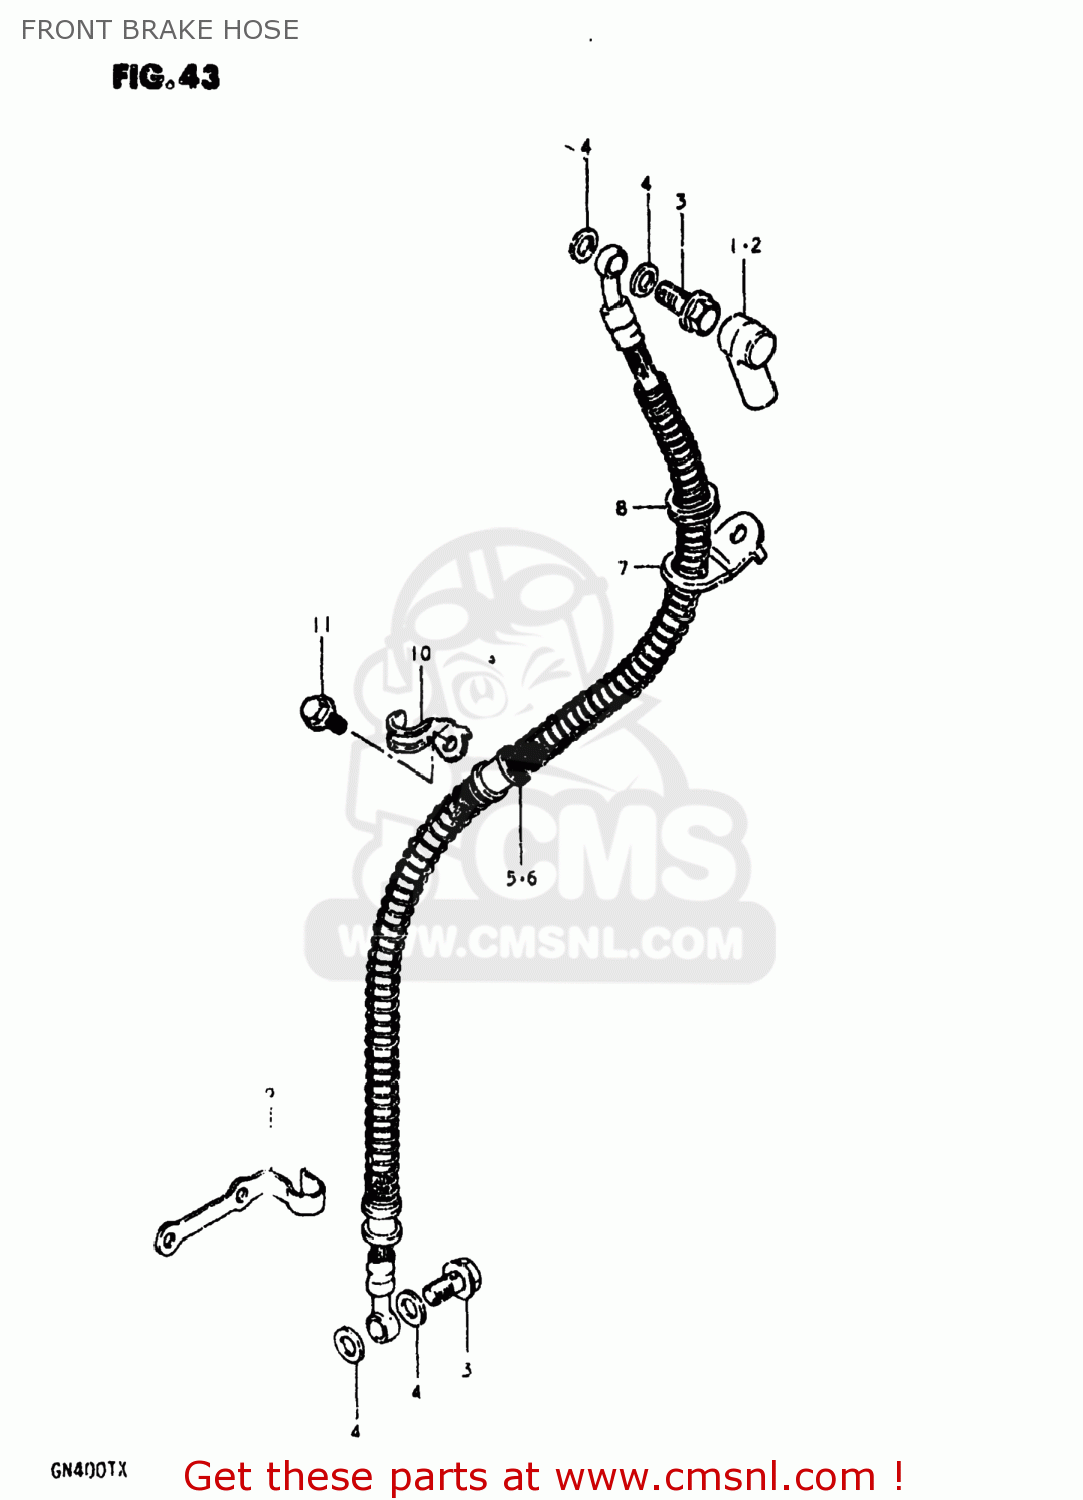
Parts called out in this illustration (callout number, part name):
1	BOOT,MASTER CYLINDER
2	BOOT,MASTER CYLINDER
3	BOLT,UNION
4	WASHER
5	HOSE,FRONT BRAKE
6	HOSE,FRONT BRAKE
7	GUIDE,BRAKE HOSE
8	GROMMET
9	GUIDE,BRAKE HOSE NO.2
10	GUIDE,BRAKE HOSE NO.3
11	BOLT
